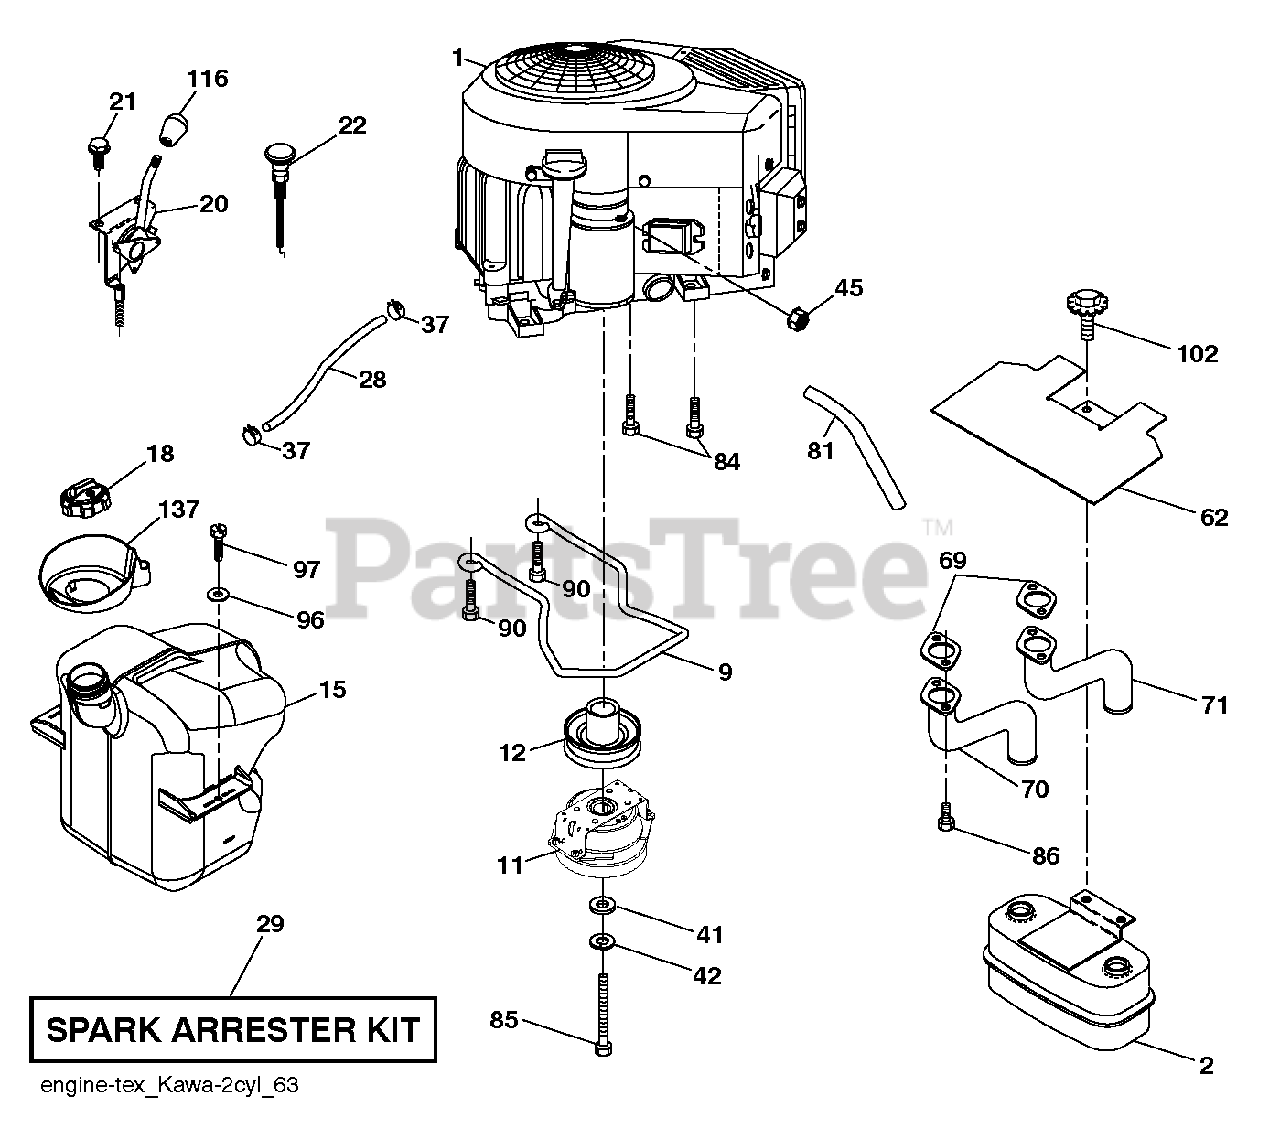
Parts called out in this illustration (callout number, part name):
2	MUFFLER.ASM.TWN.EXTNDED.DFLCTR
9	KEEPER.BELT.ENG.4.25"2.BLT.431
11	CLUTCH.OGURA.5.0PD.GT1.5A-EH07
12	PULLEY.ENGINE.TUFFTORQ
15	FUEL TANK TANK. ASSEMBLY. EXTE
18	CAP.ASM.FUEL.2.25"TOP.TURN
20	CONTROL.THROTTLE.PRO.
21	SCREW.#10 X 0.750.BOS
22	CONTROL.CHOKE.ERGO.PUSH-IN.BLA
28	LINE.FUEL.20
29	KIT.SPARK ARRESTOR 794945 B&S
37	HOSE CLAMP
42	WASHER 7/16 LOCK
45	NUT
62	SHIELD.HEAT.MUFFLER
70	TUBE.EXHAUST.LH.FR961/FR730
71	TUBE.EXHAUST.RH.FR961/FR730
81	TUBE, DRAIN OIL ASM.
84	SCREW 3/8-16X1
85	BOLT.HEX.7/16-20X3.75.GR5.RED
86	NUT.HEX.FLANGE.TOPLOCK
90	SCREW 3/8-16X1
97	SCREW HEXWSHR 1/4-20X3/4
102	SCREW
116	KNOB - SHIFT
